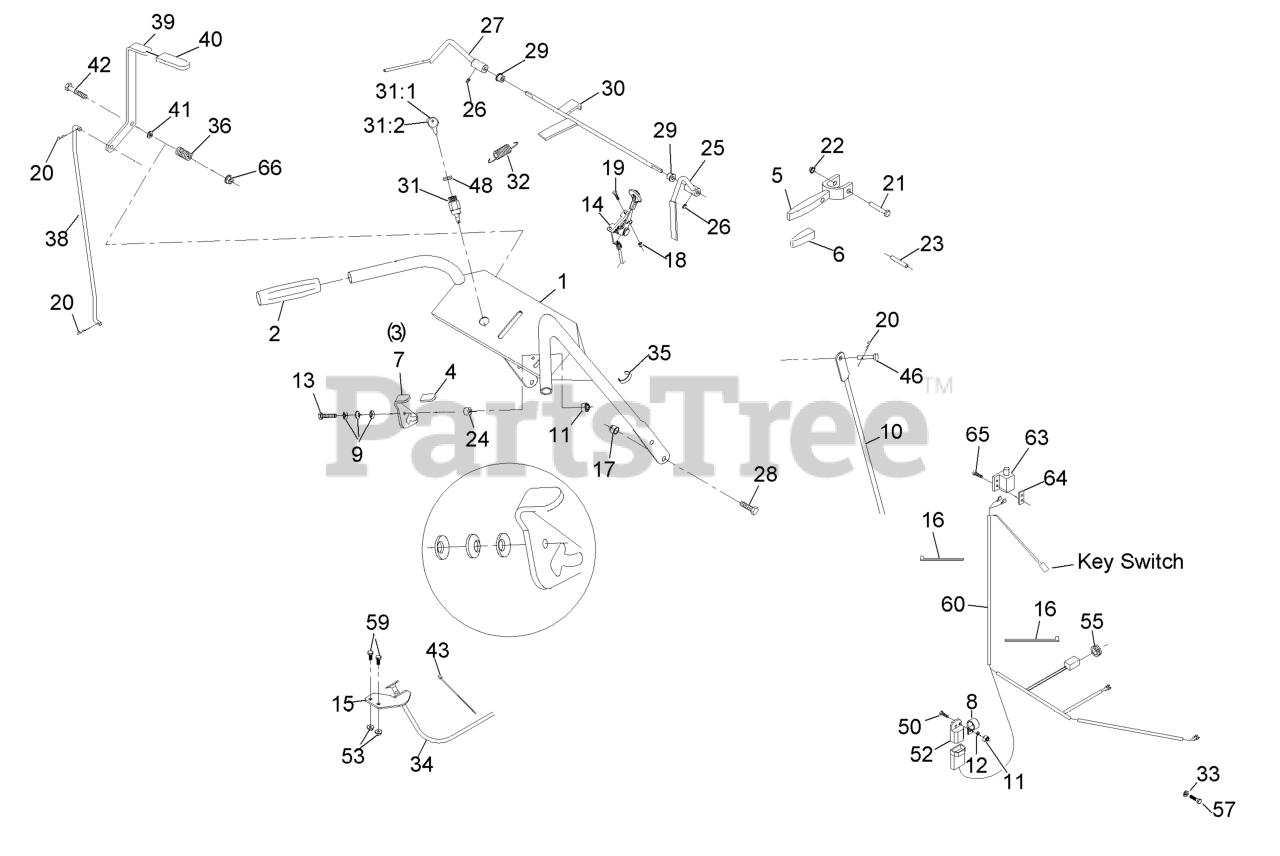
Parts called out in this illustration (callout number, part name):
1	KIT,HANDLE W/DECALS METRO
4	GRIP-LATCH
5	DRIVE LEVER ASM
6	GRIP-LEVER, DRIVE
8	CLIP-LOOM
9	WASHER-SPRING
10	LINKAGE-WHEEL, DRIVE
11	NUT-LOCK, NI
12	WASHER-FLAT
13	SCREW-HH
14	CONTROL, THROTTLE
15	BRACKET-CABLE, CHOKE
16	TIE-CABLE
17	NUT-LOCK, NI
18	NUT-LOCK, NI
19	BOLT-CARR
20	PIN-COTTER
21	PIN-LEVER, DRIVE
22	NUT-PUSH
23	PIN-ROLL
25	LEVER-RH
26	SCREW-SET
27	LEVER-LH
28	SCREW-HH
29	BUSHING-NYLON
30	WLD,ROD OPC
31	SWITCH & KEY (INCLUDES NU
31:1	KEYS-IGNITION (SPARE PAIR
31:2	KEY-IGNITION
32	SPRING-EXTENSION
33	WASHER-PLAIN
34	CABLE-CHOKE
35	CLIP-CABLE
36	SPRING-COMPRESSION
38	LINKAGE-BLADE, UPPER
39	LEVER ASM
40	GRIP-LEVER
41	WASHER-FLAT
42	SCREW-HH
43	TIE-PLASTIC
46	PIN-CLEVIS
48	NUT-SWITCH, IGNITION
50	SCREW-HH
52	MODULE-INTERLOCK
55	GROMMET
57	SCREW-HH
59	SCREW-HH
60	HARNESS-WIRE
63	SWITCH-OPEN, NORMALLY
64	PLATE-TAPPED
65	SCREW-PPH
66	NUT-HF, NI
